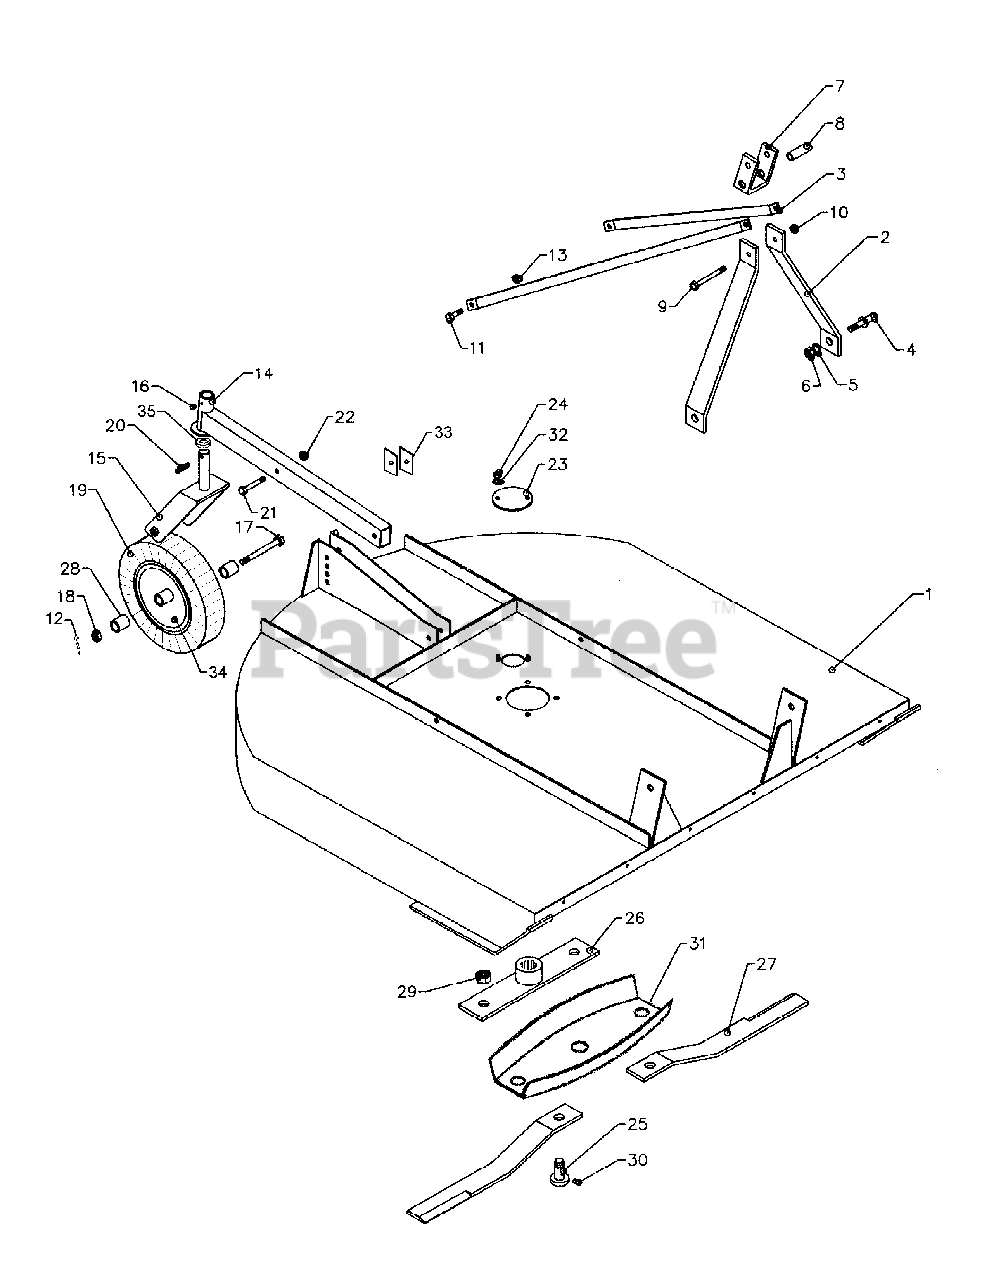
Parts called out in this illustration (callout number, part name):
1	Frame RC60 (round back deck)
1	Frame RC72 (round back deck)
2	Vertical support
3	Horizontal support (RC60 & RC72)
4	Hitch pin 7/8"x3"
5	Lock washer 7/8"
6	Hex nut 7/8"
7	Top hitch plate
8	Inner spacer
9	Bolt 5/8"x6.5"
10	Stover nut 5/8"
11	Bolt M14x40
12	Cotter pin
13	Stover nut M14
14	Wheel arm (RC60 & RC72)
16	Grease fitting
17	Bolt M24x185
19	Laminated wheel complete
20	Roll pin Ø10x50
21	Bolt M16x90
22	Stover nut M16
23	Access plate (RC60 & RC72)
24	Nylock nut M10 (RC60 & RC72)
25	Blade bolt (RC60 & RC72)
26	Rotor (RC60 & RC72)
27	Blade (RC60)
27	Blade (RC72)
28	Wheel bushing
29	Nut M27
30	Blade stop pin
31	Stump jumper (RC60 & RC72)
32	Flat washer M10 (RC60 & RC72)
34	Grease fitting
35	Flat washer Ø33x56x4
